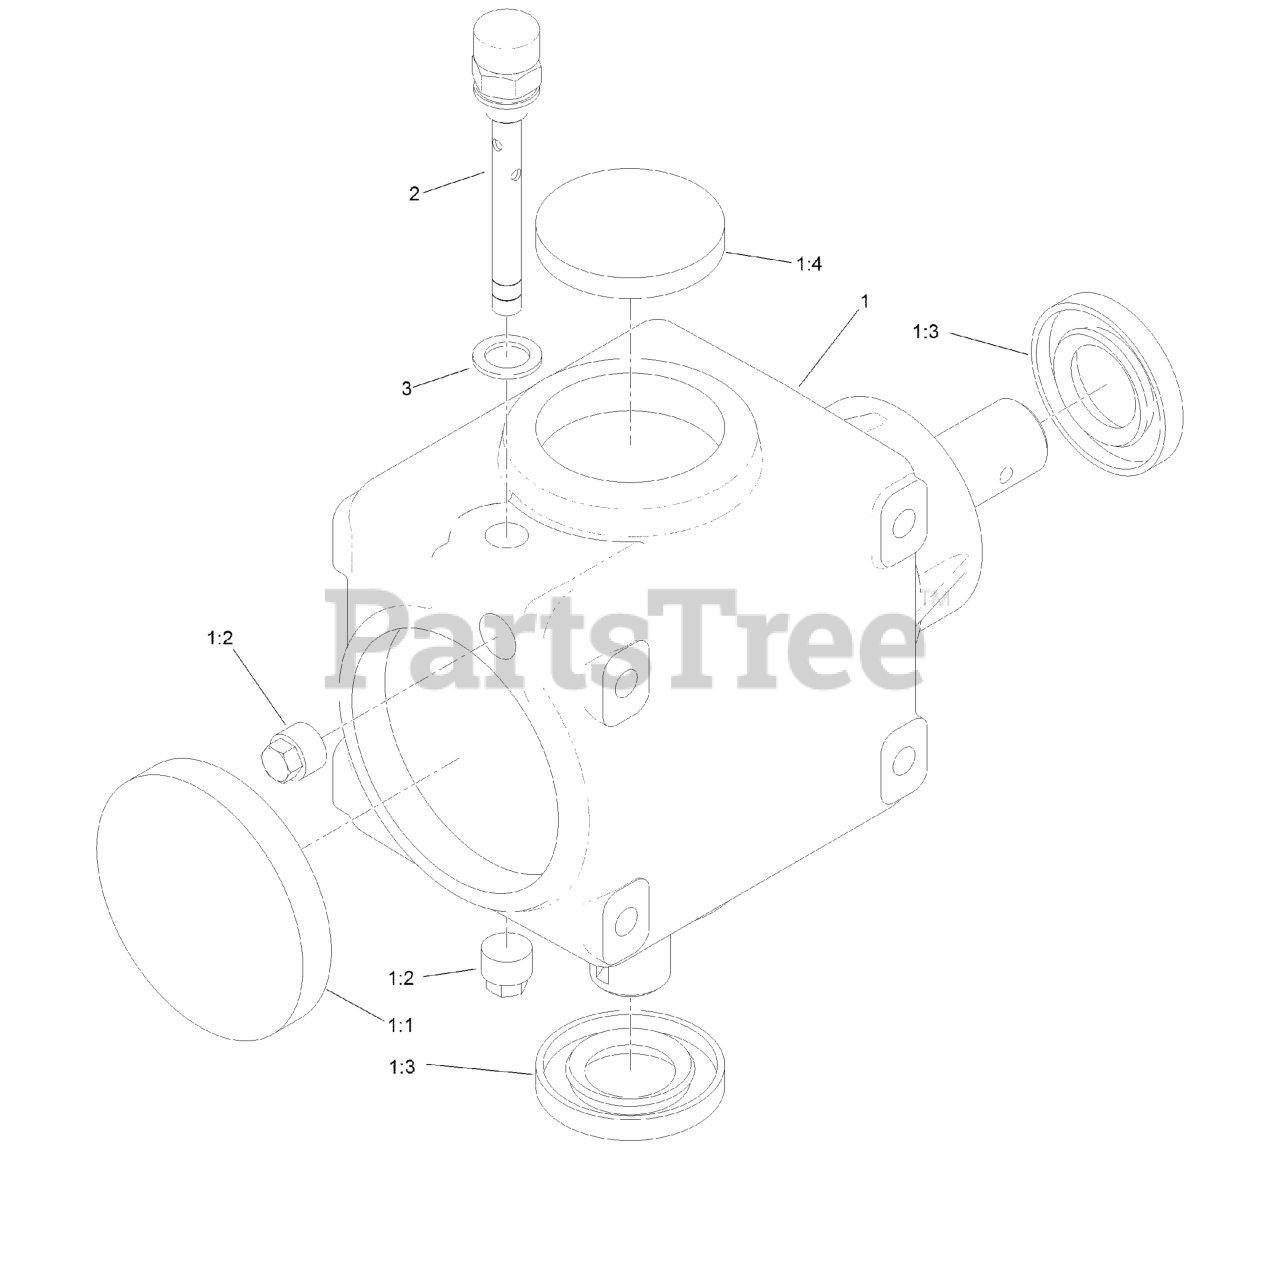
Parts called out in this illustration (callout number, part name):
1	Gearbox ASM
1:1	CAP-OIL
1:4	CAP-OIL
2	PLUG-BREATHER
